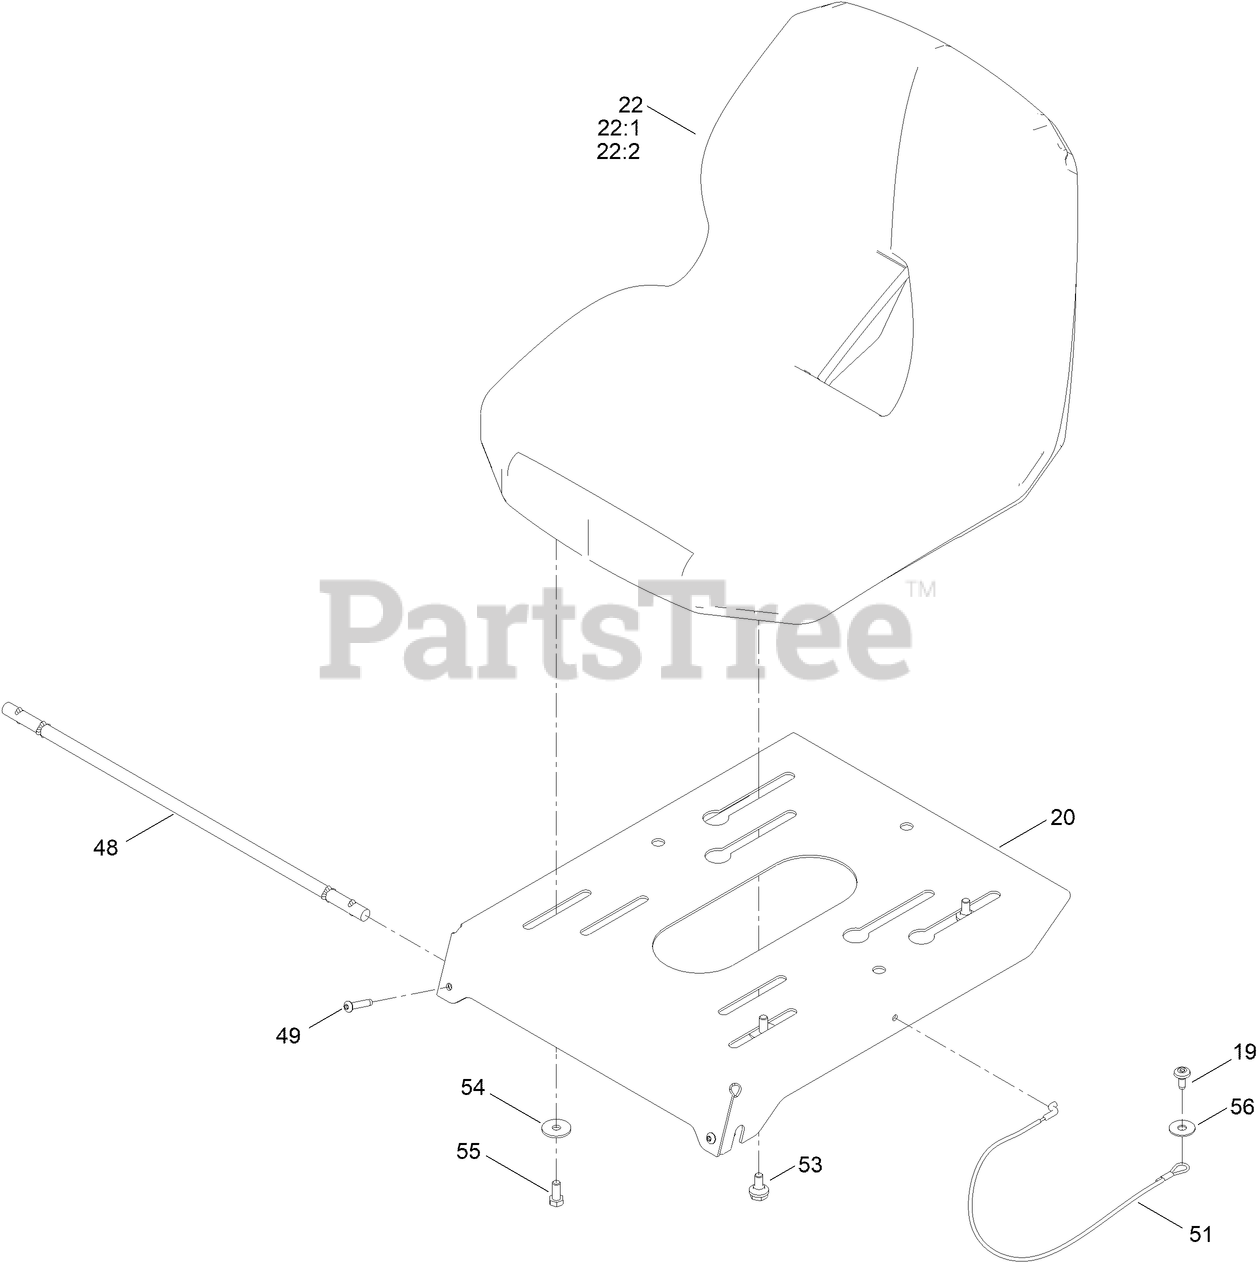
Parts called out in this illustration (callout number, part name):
19	SCREW-SHOULDER
20	PAN-SEAT
22	SEAT-16 IN
22:1	SEAT-16 IN
22:2	SWITCH-BAIL
48	ROD-PIVOT
49	SCREW-BHCS
51	CABLE-LANYARD
53	BOLT-SHOULDER,HFH
54	WASHER-PIVOT
55	SCREW-HH
56	WASHER-FLAT
